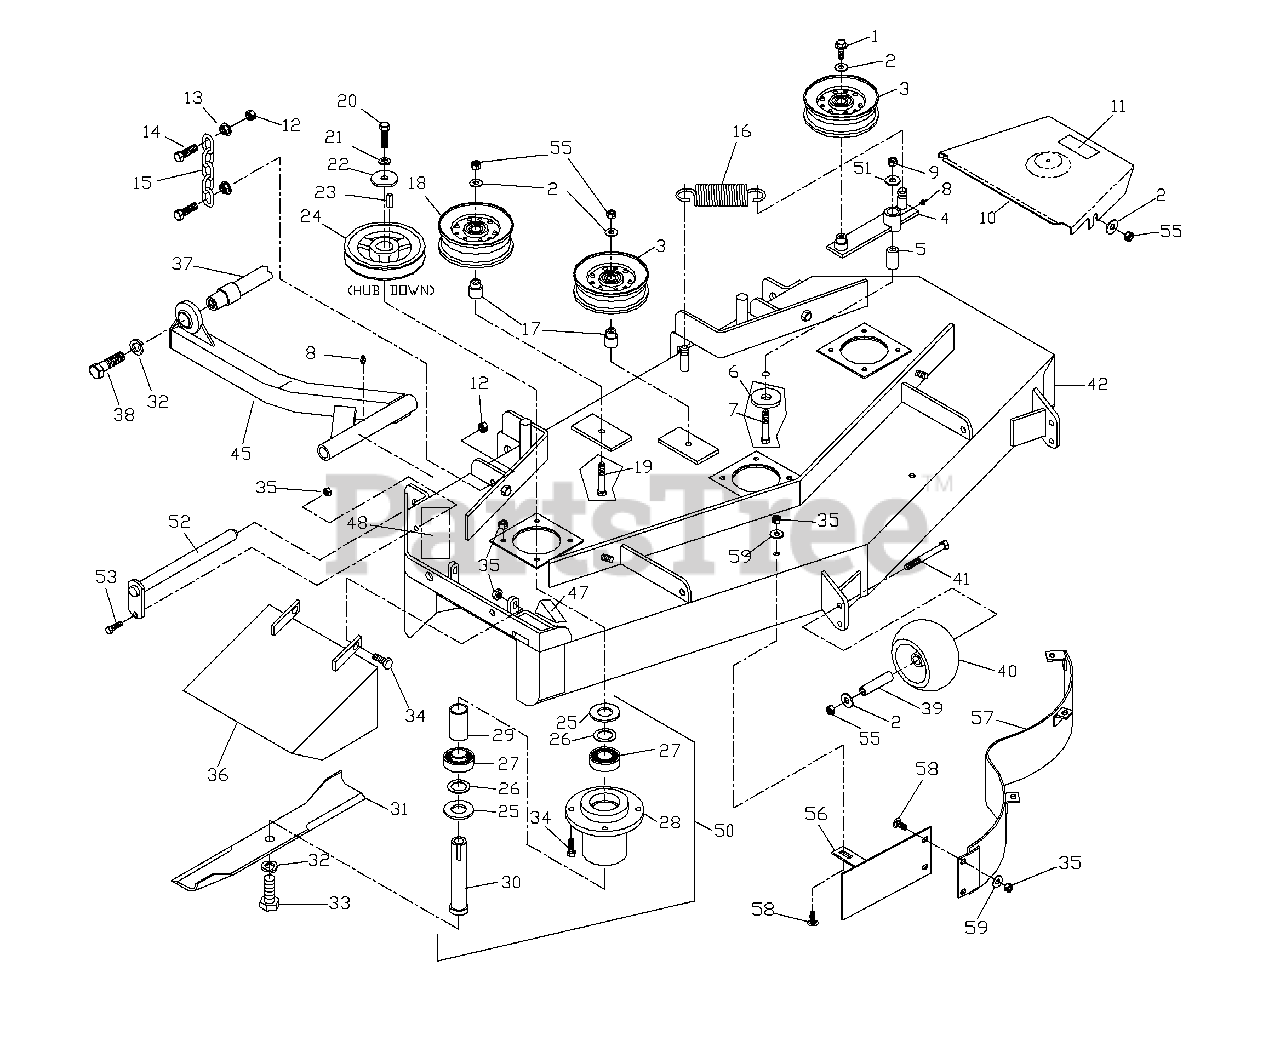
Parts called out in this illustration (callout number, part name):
1	HCS 3/8C X 1 SERRATED HD
2	WASHER 3/8 FLAT
3	IDLER PULLEY
5	PIVOT BUSHING
6	SUPPORT WASHER
7	HCS 1/2C X 3 1/4
8	ZERK
9	NUT 1/2C NYLOC
10	BELTSHIELD
11	DECAL, NO STEP
12	NUT 7/16C CENTERLOCK
13	7/16C WHIZ NUT
14	HCS 7/16C X 1 1/2
15	LIFT CHAIN
17	IDLER BUSHING
18	IDLER PULLEY(TALL)
19	HCS 3/8C X 2 1/2
20	HCS 7/16F X 1 1/2
21	LOCKWASHER 7/16
22	HEAVY WASHER
23	KEY 1/4 SQ. X 1 1/8
25	MACHINE BUSHING 10 GA.
26	MACHINE BUSHING 18 GA.
27	BEARING
31	16 1/4" BLADE
32	LOCKWASHER 5/8
33	HCS 5/8F X 1 1/4
34	HCS 5/16C X 1
35	NUT 5/16C CENTERLOCK
36	DEFLECTOR CHUTE
37	STRUT MOUNT WLDMT
38	HCS 5/8C X 2 GR.5
40	ANTI-SCALP ROLLER
41	HCS 3/8C X 3 1/2
42	DECK W/DECALS
45	STRUT - RT
47	DECAL, CPSC
48	DECAL, DANGER
50	COMPLETE HOUSING
51	WASHER 1/2 FLAT
53	HCS 5/16C X 3/4
55	NUT 3/8C CENTERLOCK
56	CENTER BAFFLE
57	MAIN BAFFLE
58	CARRIAGE BOLT
59	5/16 FLAT WASHER
